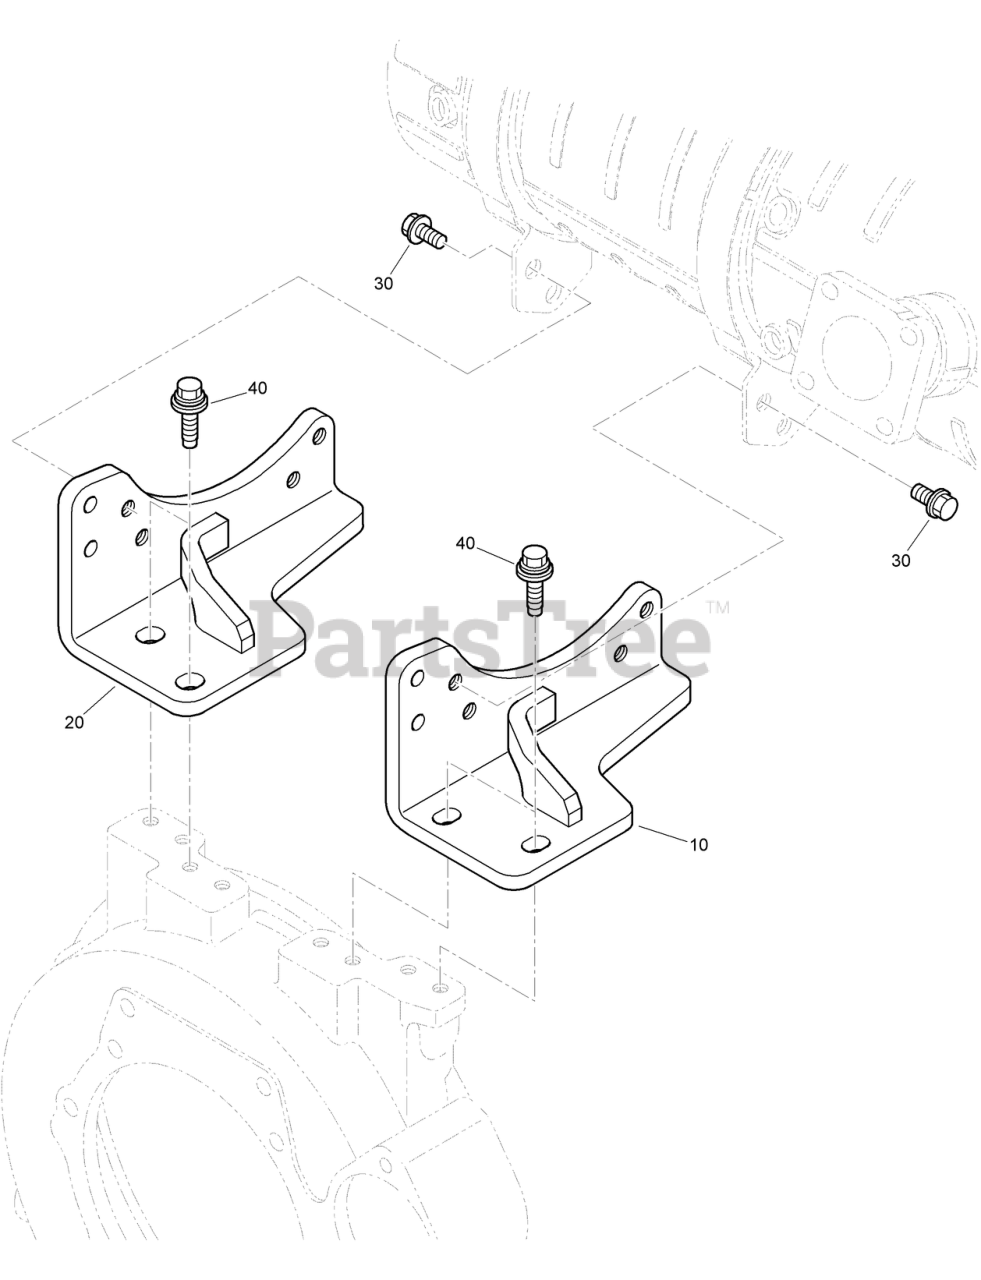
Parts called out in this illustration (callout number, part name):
10	BRACKET-D P F 1
20	BRACKET-D P F 2
30	BOLT-FLANGE
